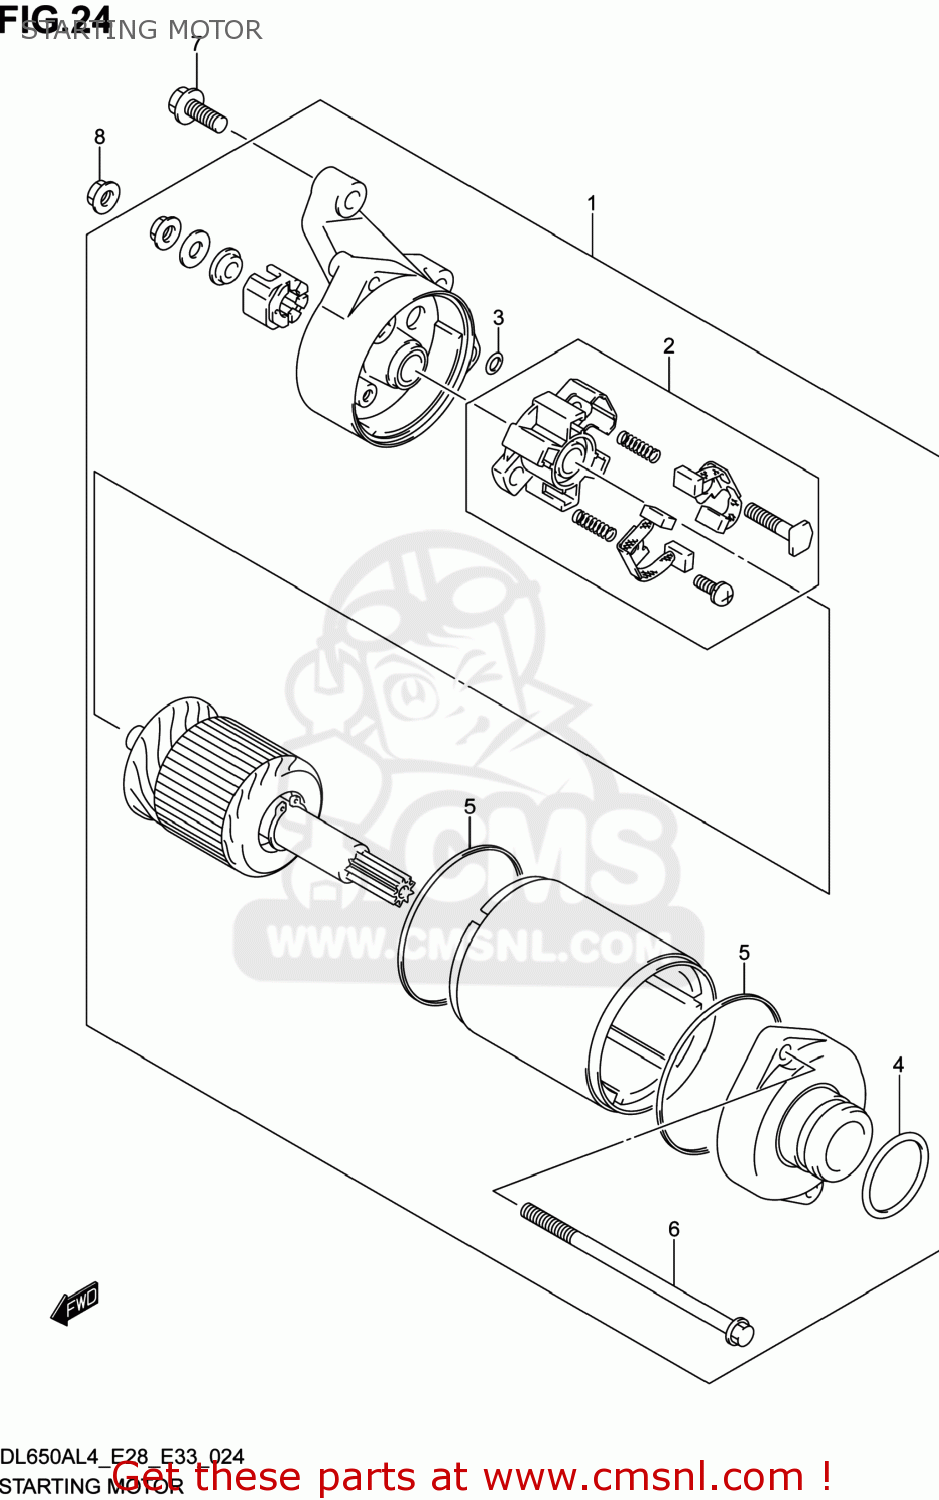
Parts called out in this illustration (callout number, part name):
1	MOTOR ASSY,STARTING
2	BRUSH HOLDER SET
3	O RING
4	O RING
5	SQUARE RING
6	SET,BOLT
7	BOLT(6X25)
8	NUT
